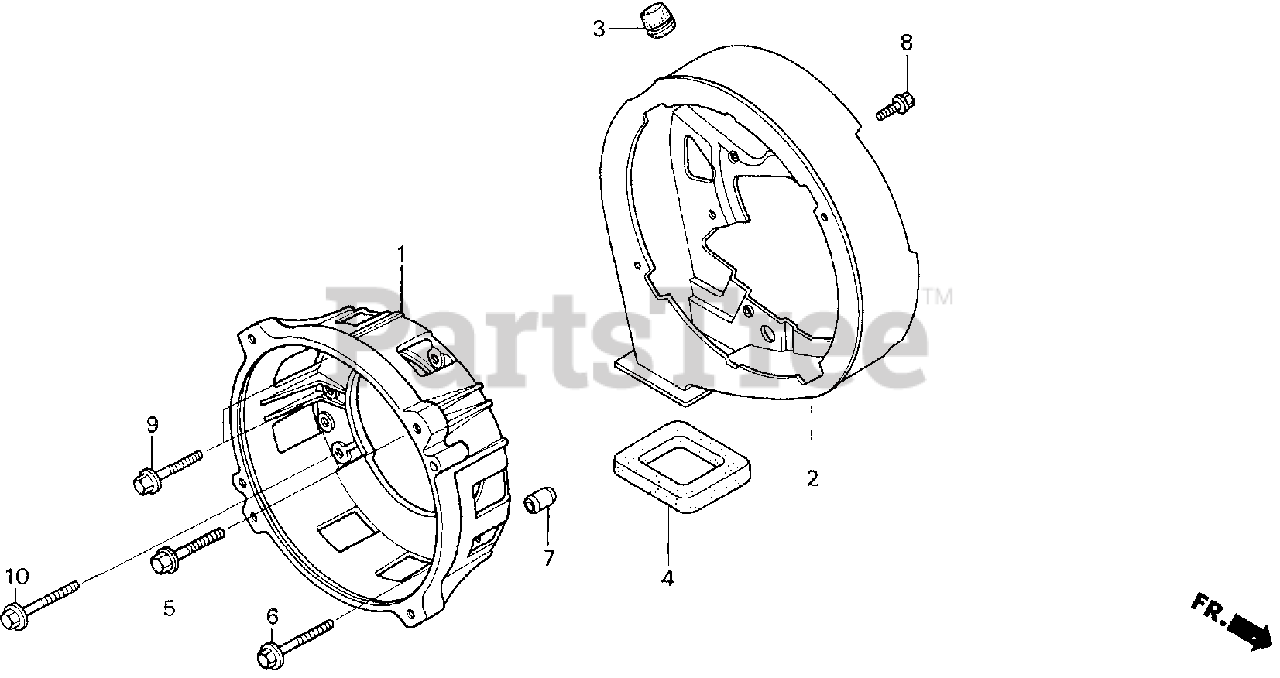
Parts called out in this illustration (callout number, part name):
1	HOUSING, FR.
2	COVER, DUCT
3	GROMMET, DUCT COVER
5	BOLT, FLANGE (8X32)
6	BOLT, FLANGE (8X40)
7	PIN A, DOWEL (10X14)
8	BOLT, FLANGE (6X12)
9	BOLT, FLANGE (8X32)
10	BOLT, FLANGE (8X40)
